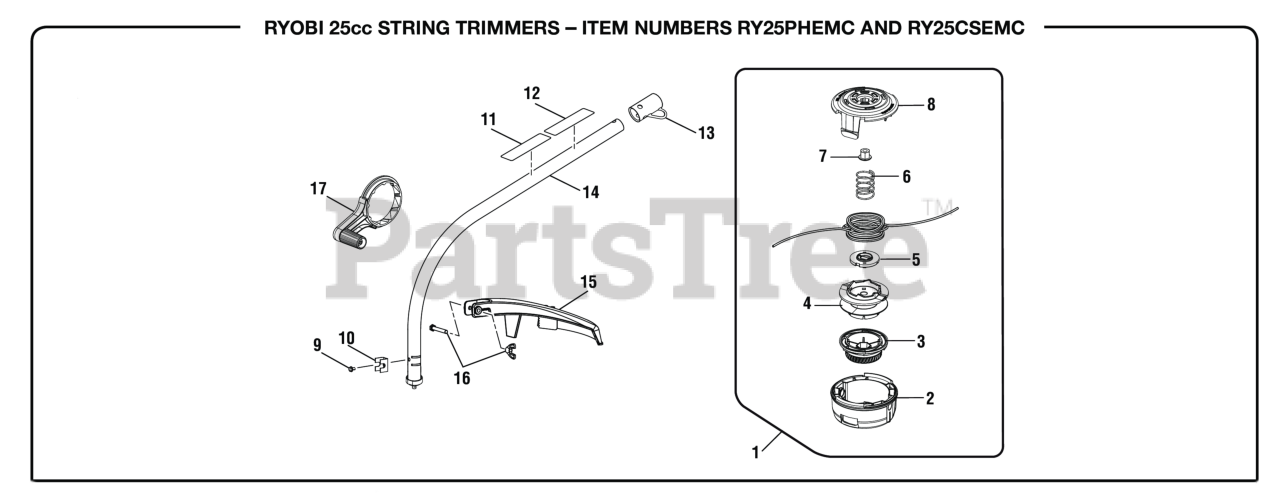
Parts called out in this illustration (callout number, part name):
1	Trimmer Head Assembly (.095)
2	Lower Housing
3	Bump Knob (Green)
4	Spool Assembly
5	String Guide
6	Compression Spring
7	Flange Nut (M8)
8	Upper Housing
9	Screw (#10-32 x 3/8 in., Hex Washer Hd. S.T.)
11	Ryobi EXPAND-IT Label
12	Warning Icon Label
13	Storage Hanger Cap
14	Curved Shaft Assembly
15	Grass Deflector Assembly
16	Fastener Parts Kit
17	Crank Handle
